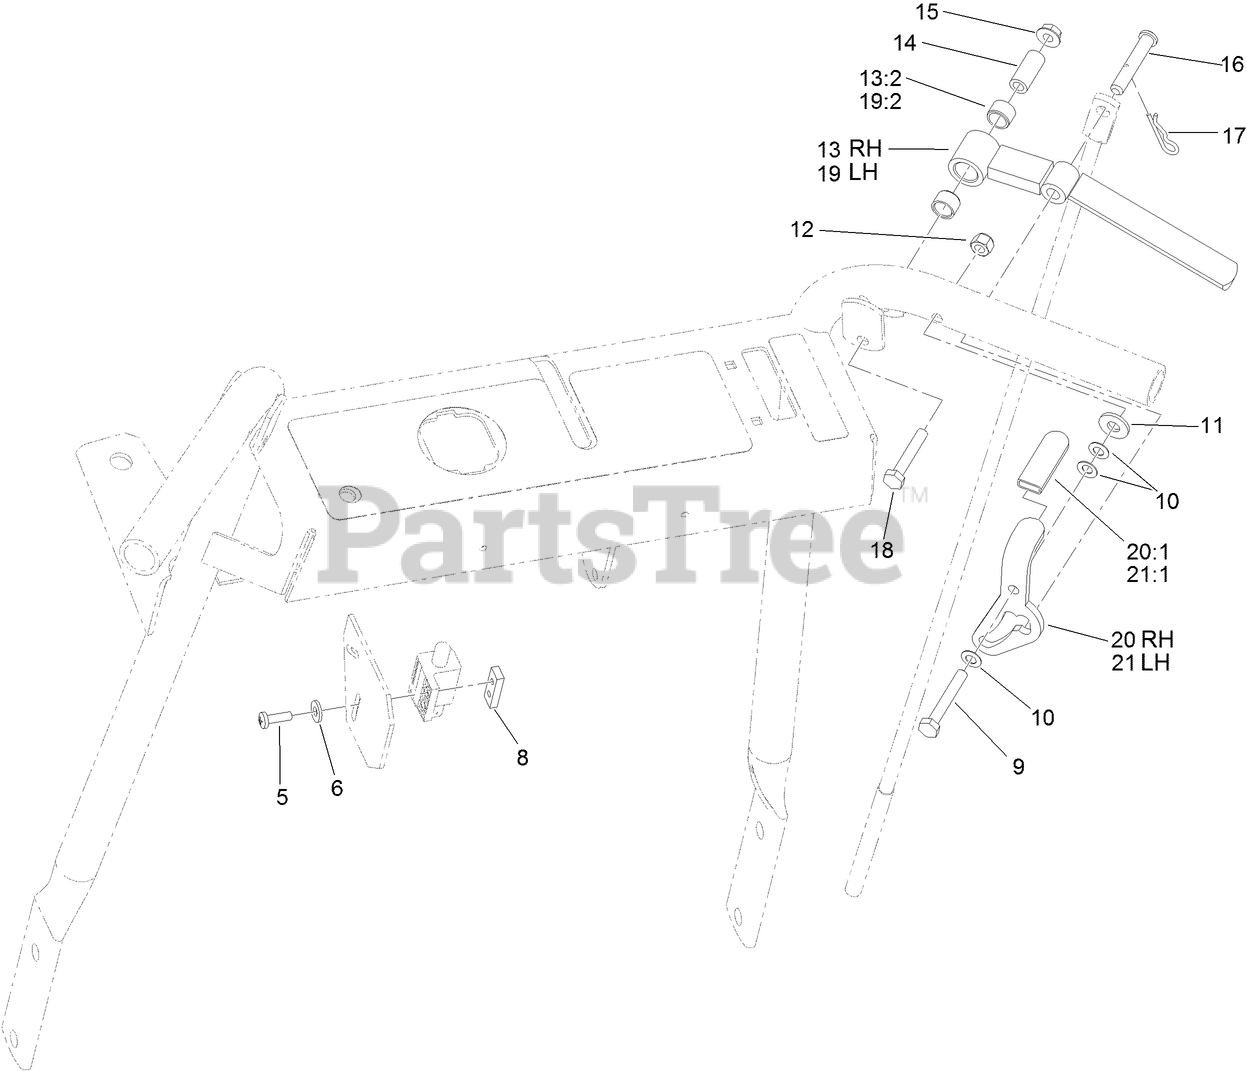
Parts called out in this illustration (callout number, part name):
5	SCREW-PPH
6	WASHER-FLAT
8	PLATE-TAPPED
9	SCREW-HH
10	WASHER-SPRING
11	WASHER-FLAT
12	NUT-LOCK, NI
13	RH Drive Lever ASM
13:2	BUSHING-SLEEVE
14	Bushing-Lever, Drive
15	NUT-HF
16	Pin-Clevis
17	PIN-COTTER
18	SCREW-HH
19	LH Drive Lever ASM
19:2	BUSHING-SLEEVE
20	RH LATCH and GRIP ASM
20:1	GRIP-LATCH
21	LH LATCH GRIP ASM
21:1	GRIP-LATCH
